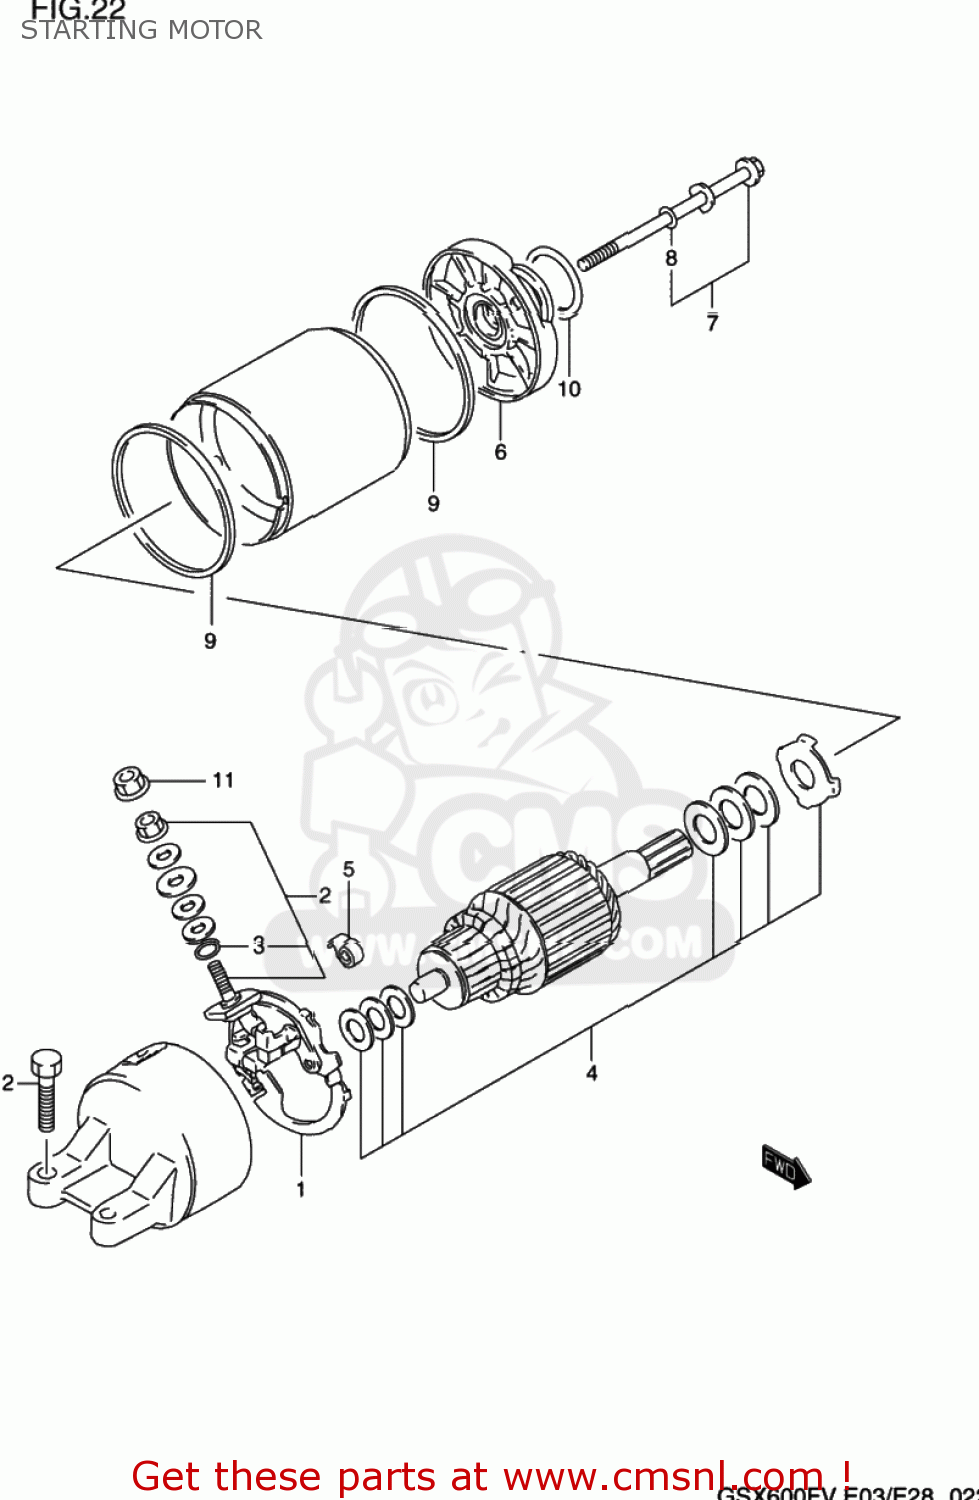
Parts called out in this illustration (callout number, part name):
1	HOLDER SET,BRUSH
2	TERMINAL SET,BRUSH,PLUS
3	O RING
4	SHIM SET,STARTING MOTOR
5	SPRING,BRUSH
6	BRACKET ASSY,FR
7	BOLT SET,STARTING MOTOR
8	O RING
9	O RING
10	O RING(D:3,ID:24.5)
11	NUT
12	SCREW (6X25)
